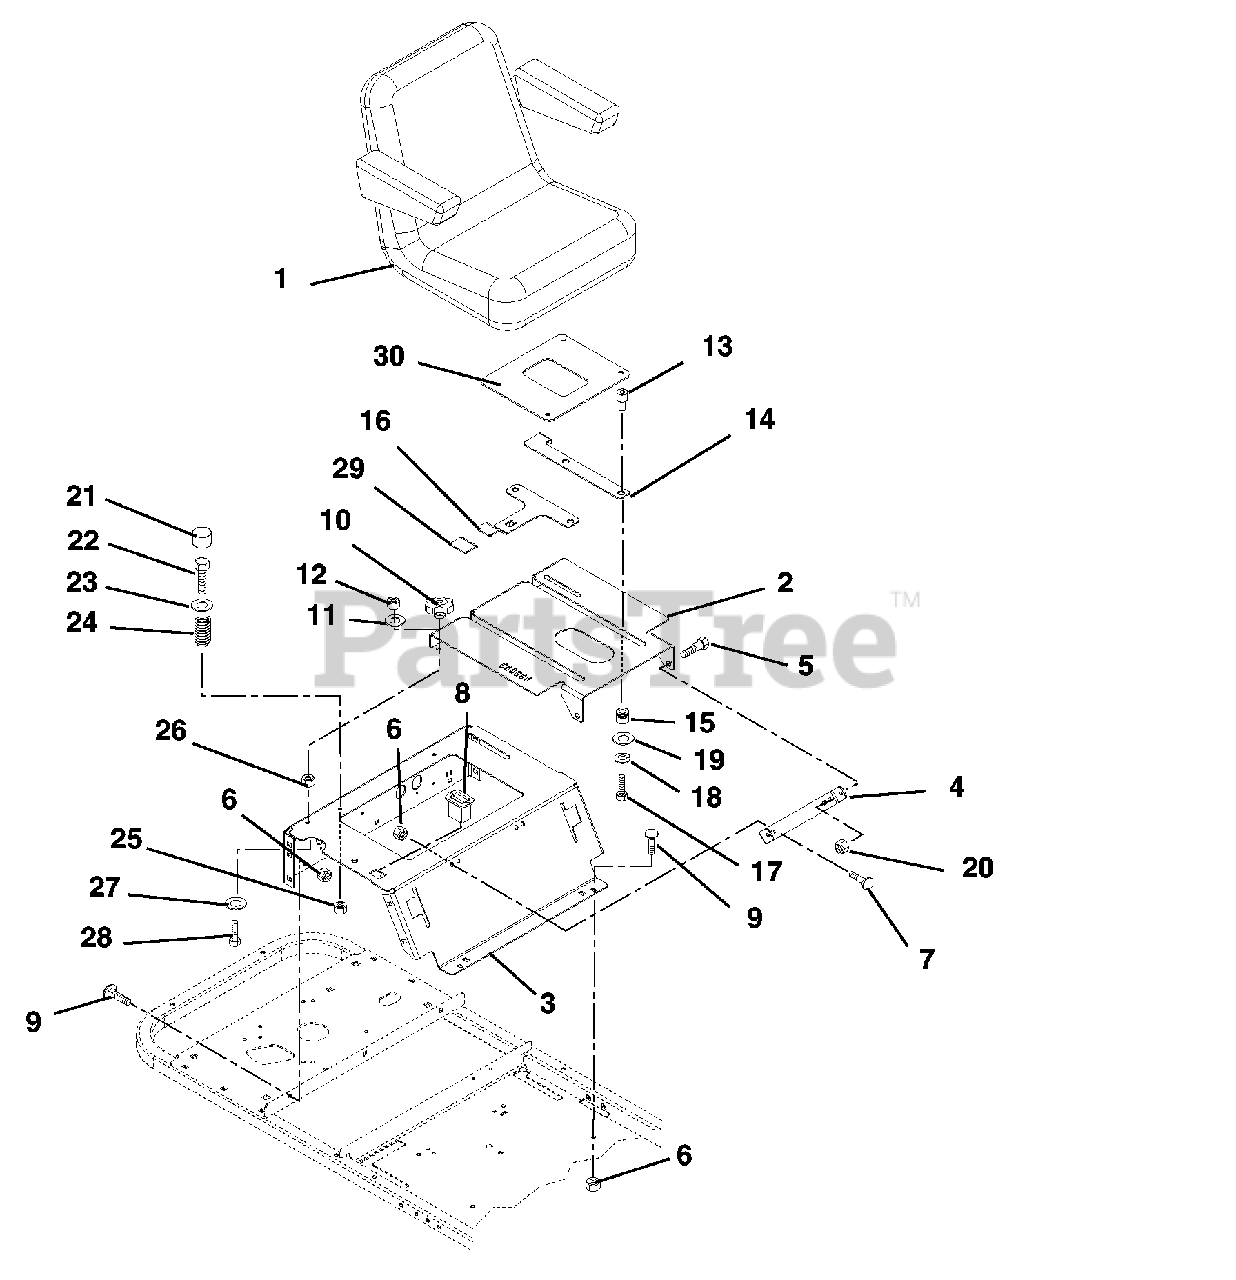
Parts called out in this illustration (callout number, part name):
2	Seat Plate
3	Seat Support
4	Bracket, Seat Plate
5	Bolt, Shoulder .375-16 x .135
6	Nut .38-16 Flange Nyloc
7	Bolt, Round Head Square Neck .38-16 x 1.00 Grade 5
8	Hour Meter, Quartz
9	Bolt, Round Head Square Neck .38-16 x 1.00 Grade 5
10	Knob, Clamping .312-18 Nyloc
11	Washer-Flat-Steel .328 x 1.00 x .094
12	Nut, Locking Nylon .312-18
13	Spacer, Seat Top
14	Seat Stop
15	Spacer, Seat Bottom
16	Lever, Seat Adjustment
17	Bolt-Hex .31-18 x 2.25 Grade 5
18	Washer-Locking .31 x .078 Regular
19	Washer-Flat-STL.312 x .734 x .065
20	Nut-Locking-Top-Flange .38-16
21	Hub Cap
22	Bolt-Hex .31-18 x 1.00 Grade 5
23	Washer-Flat-Steel .328 x 1.0 x .094
24	SG. Compression 2.9L x 2.02OD 200LB
25	Nut 5/16-18 Flange Nyloc
26	Nut-Spin Lock-Flange .312-18
27	Washer-Flat-Steel .505 x 1.00 x .062
28	Bolt-Round Head Square Neck .31-18 x 3.50 Grade 5
30	Seat Support Plate
